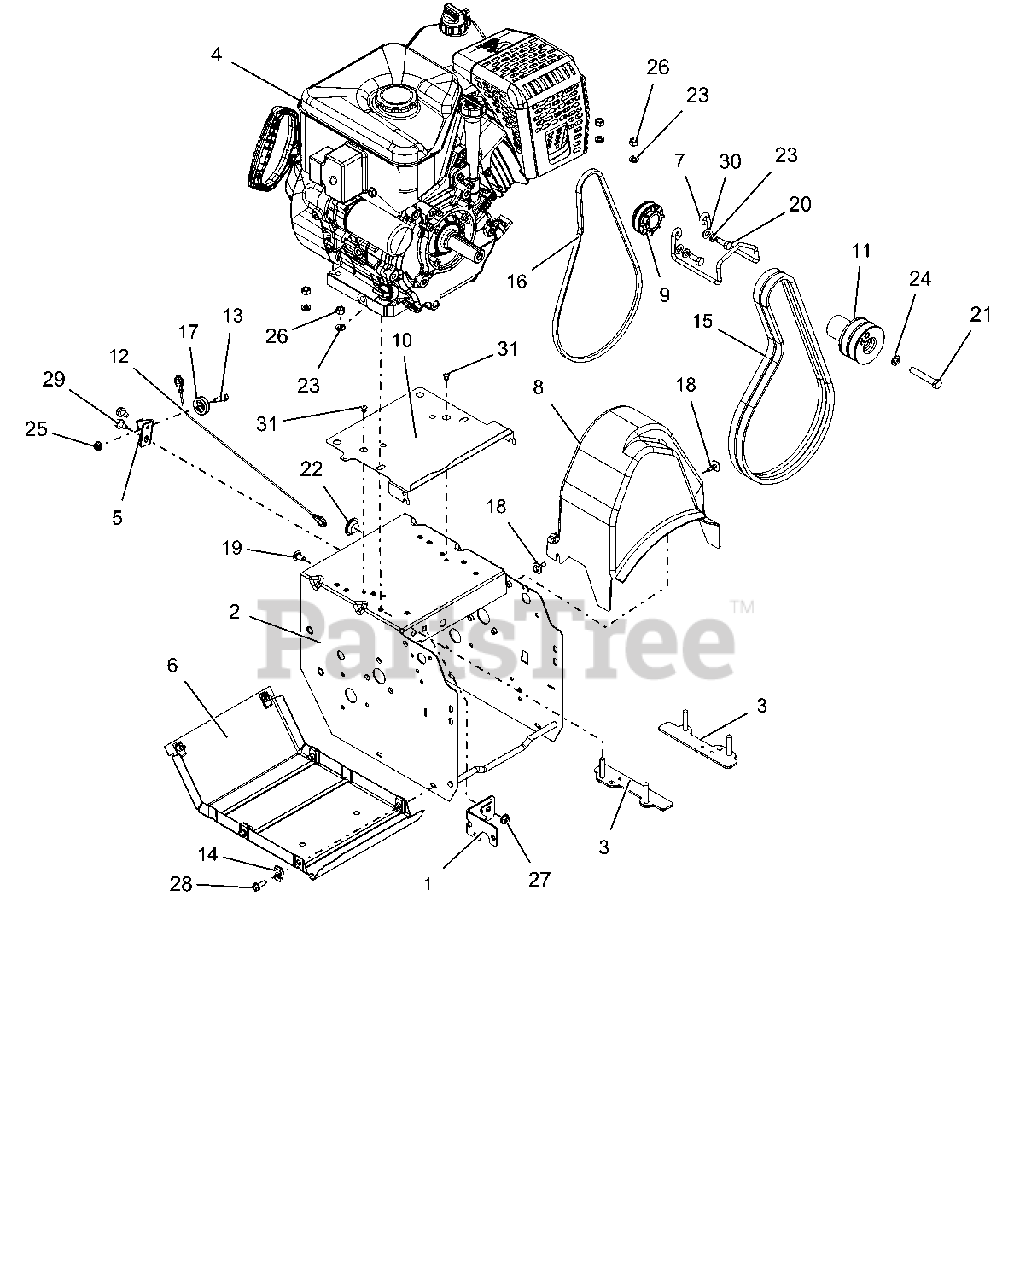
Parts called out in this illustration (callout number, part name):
1	WELDMENT, FRAME BRACKET
2	WELDMENT, FRAME - DELUXE 16"
3	STRAP,ENGINE BOLT,ARIENS LRG
4	ENGINE, AX369 GEN 3 120V/60W
5	BRACKET, CABLE PULLEY
6	COVER, BOTTOM
7	FINGER, BELT
8	BELT COVER
9	SHEAVE, DRIVE
10	BAFFLE,ENGINE,ARIENS LRG BLOCK
11	SHEAVE,ATTACHMENT 2-GRV
12	CABLE, LOWER TRACTION (DELUXE)
13	BOLT, SHLDR-.375X.375X.25-20
14	NUT-RTNR .25-20X.56
15	V-BELT, HA-RAW EDGE (SET)
16	V-BELT, 3L-RAW EDGE
17	PULLEY, CABLE
18	SCR-TAP .25-20X.5 CAPTIVE
19	@BLT-RHDSSQNK .31-18X.62 G5YZ
20	BLT-HEX .31-24X.75 YWZC GR5
21	BLT-HEX .38-24X2.25 YWZC GR5
22	PLUG, HOLE - .875" NYLON
23	WSHR-LK .312X.097 HVY YWZC
24	@WSHR-LK .38X.094 REG YWZC
25	@NUT-LK-CTR-FLG .25-20 YWZC
26	@NUT-HEX .31-18 YWZC
27	@NUT-LK-TOP-FLG .31-18 YWZC
28	BLT-HEX .25-20X.75 HWH YZ GR5
29	@SCR-TAP .31-18X.50 HWH TR YWZ
30	@WSHR-FL-STL.344X.688X.065YWZC
31	RVT-POP .187 YZ
